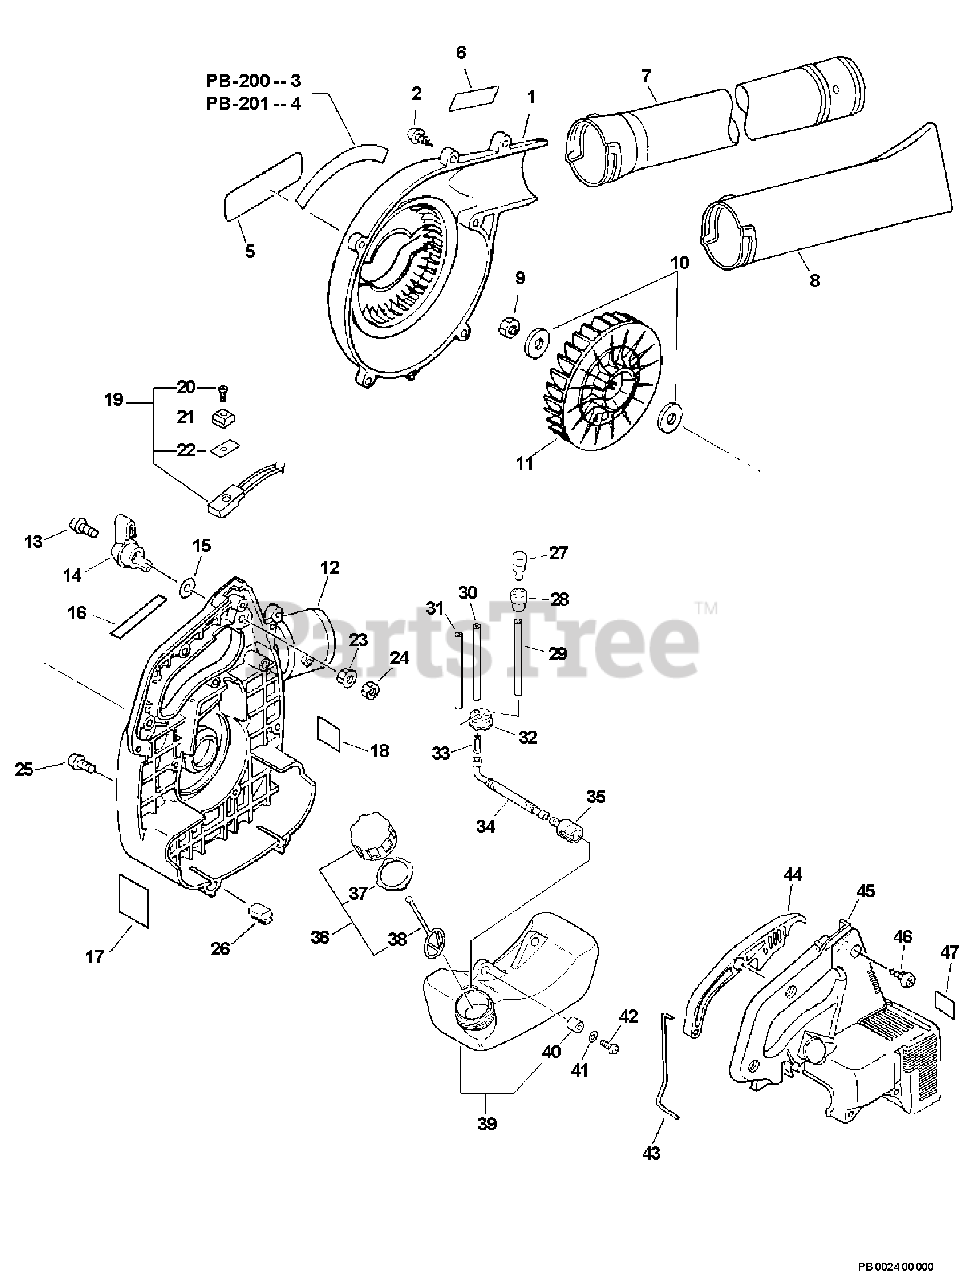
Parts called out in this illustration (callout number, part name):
1	COVER, FAN
2	SCREW, TAPPING 5×20
3	LABEL - MODEL PB-200
4	LABEL, MODEL
5	LABEL - ECHO
6	LABEL - NOISE
7	TUBE, BLOWER - STRAIGHT
8	TUBE, BLOWER - NOZZLE
12	COVER, FAN - RIGHT
13	SCREW 5×25
14	CONTROL, THROTTLE
15	WASHER 5.5×12×0.8
16	LABEL, CAUTION - ISO
17	LABEL - CAUTION -- SPANISH
18	LABEL - CAUTION
19	CABLE ASSY, CONTROL
20	SCREW 3×10
21	KNOB, SWITCH - ORANGE
22	LABEL, SWITCH
23	NUT, FLANGE M5
25	SCREW 4×22
27	VENT ASSY
28	HOLDER, VENT
29	PIPE, FUEL 3x-5x-70 BLACK
30	PIPE, FUEL 3×5×90 BLACK
31	PIPE, FUEL RETURN 3×6×90 MM CLEAR
32	GROMMET, FUEL
33	CONNECTOR, PIPE
34	PIPE, FUEL - CORRUGATED
35	FILTER, FUEL
36	CAP ASSY, FUEL
37	GASKET, FUEL CAP
38	CONNECTOR, CAP L= 100 MM
39	TANK ASSY, FUEL
40	SPACER 6.2×7.8×6
41	WASHER 5.5×12×0.8
42	SCREW 5×16
43	ROD, THROTTLE
44	CONTROL, THROTTLE
45	COVER, ENGINE
46	SCREW, TAPPING 5×20
47	LABEL, CAUTION - HOT
